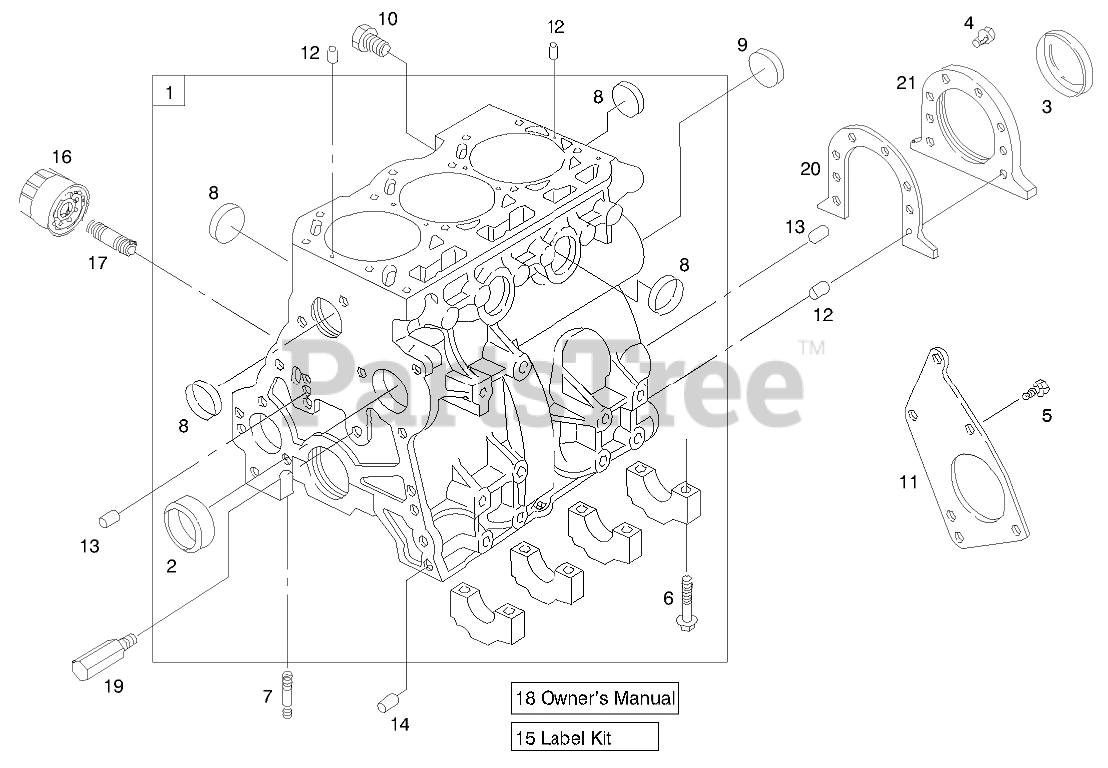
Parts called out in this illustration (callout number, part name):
1	CYLINDER ASSEMBLY
1	HEAD-CYLINDER
2	BUSHING
3	SEAL-OIL
4	SCREW-HEX
5	SCREW-HEX
6	SCREW-HEX
7	STUD-METRIC
8	PLUG-WELCH
8	SWITCH-TEMPERATURE, WATER
9	PLUG-WELCH
9	GASKET-SET
10	PLUG (CYLINDER BLOCK)
11	BRACKET-MOUNTING
12	PIN-LOCATING
13	PIN-LOCATING
14	PIN-LOCATING
14	KIT-VALVE OVERHAUL
15	LABEL KIT
15	SHAFT-GEAR
16	FILTER-OIL
17	ADAPTER-FILTER, OIL
18	MANUAL-OWNERS
19	NOZZLE-OIL
20	GASKET-RETAINER
21	RETAINER-SEAL
